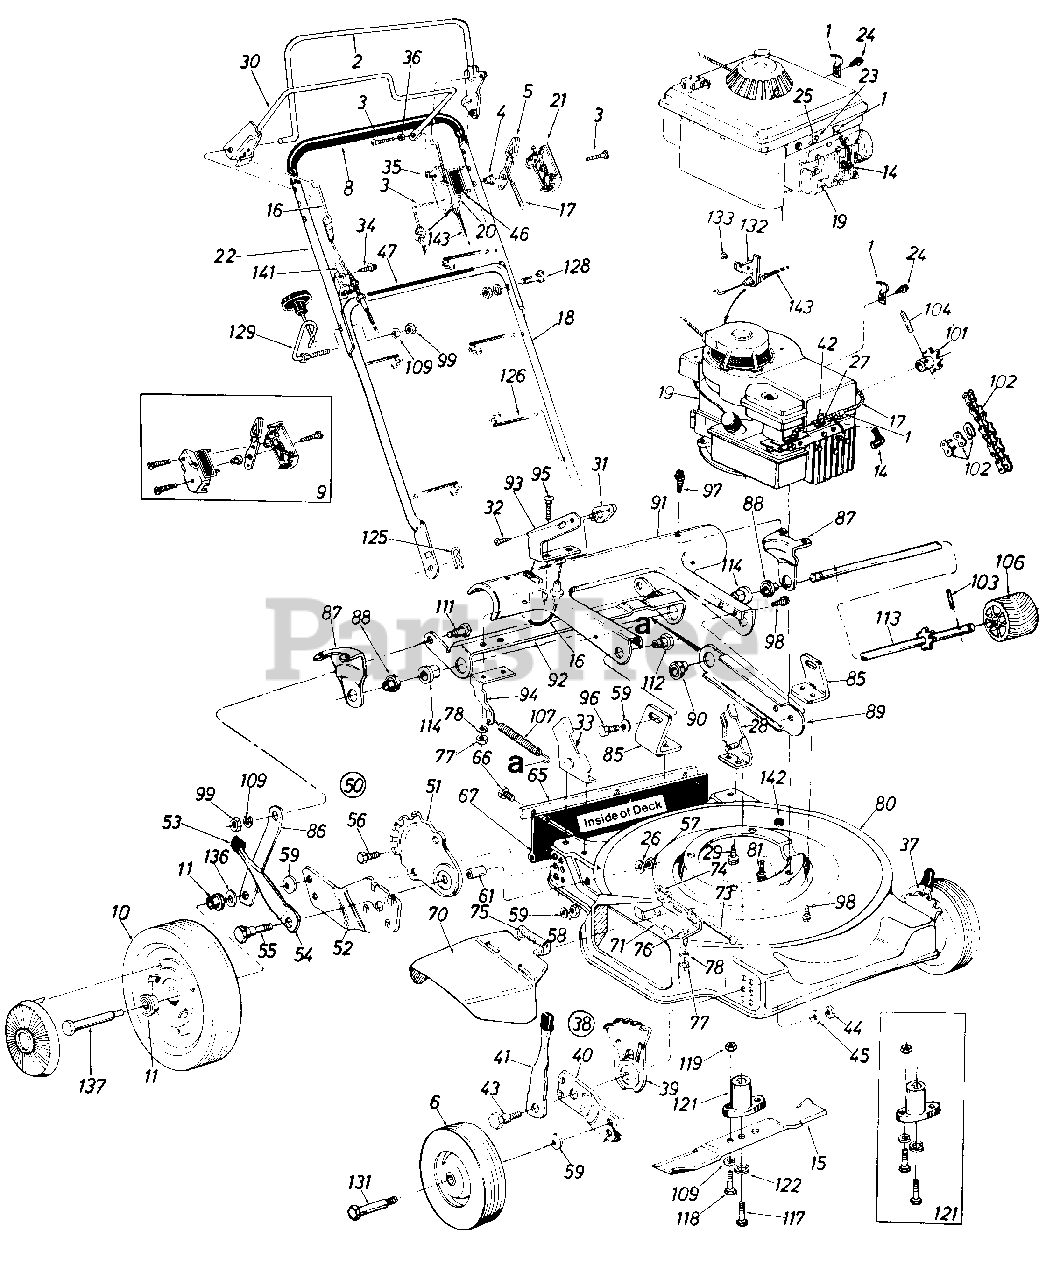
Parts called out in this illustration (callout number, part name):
1	Casing Clamp
2	Control Handle Ass'y.-L.H.
3	Truss Mach. Hi-B Tap Scr. #12 x 1.5"
4	Control Disc Pin
5	Throttle Control Lever
6	Front Wheel Ass'y. Comp.
8	Grip
9	Control Housing Comp.
10	Rear Wheel Ass'y. Comp.
11	Fl. Ball Brg. 1/2" I.D.
14	Spark Plug Insulator
15	22" Blade
16	Clutch Cable w/Spring-33"
17	Throttle Wire-53"
18	Lower Handle (Chrome)
19	Engine
20	Clutch Panel Half
21	Control Panel Half
22	Upper Handle (Chrome)
23	Hex AB-Tap Scr. #8 x .50"
24	Hex B-Tap Scr. #10 x .38"
25	Casing Clamp
26	Bell-Wash. 5/16" I.D.
27	Hex "B"-Tap Scr. #10 x .38"
28	Handle Brkt. Ass'y-L.H.
29	Hex B-Tap Scr. 5/16-18 x .5"
30	S.P. Bail Ass'y.
31	Barrel Cable Hold-Down R.H.
32	B-Tap Scr. #10 x .38 Lg.
33	Handle Brkt. Ass'y-R.H.
34	Hex Wash. AB-Tap Scr. 5/16 x .75"
35	Spr-Wash. .206 I.D. x .448
36	Spacer .23 I.D. x .30 O.D.
37	Front Height Adj. Ass'y.-L.H.
38	Front Height Adj. Ass'y.-R.H.
39	Height Adj. Plate
40	Pivot Bar
41	Spring Lever Ass'y. w/Knob
42	Casing Clamp
43	Shld. Bolt .50 Dia. x .430
44	Hex Nut 3/8-16 Thd.
45	Bell-Wash. .39 I.D. x 1.38 O.D.
46	Control Label
47	Instruction Label
50	Rear Height Adj. Ass'y.-R.H.
51	Index Plate
52	Pivot Bar-R.H.
53	Spring Lever Knob
54	Spring Lever
55	Shld. Bolt .50 Dia. x .433
56	Hex Bolt 3/8-16 x .75
57	Hex Cent. L-Nut 5/16-18 Thd.
58	Hex Nut 3/8-16 Thd.
59	Bell-Wash. .40 I.D. x .88 O.D.
61	Spacer .383 I.D. x .503 O.D.
65	Retaining Strip
66	Hex AB-Tap Scr. 1/4 x .62
67	Rear Flap Ass'y.
70	Chute Deflector Ass'y.
71	Adapter Plate
73	Pivot Pin
74	Push Nut 1/4"
75	Torsion Spring
76	Hex Bolt 1/4-20 x .50 Lg.
77	Hex Nut 1/4-20 Thd.
78	L-Wash. 1/4 I.D.
80	22" Deck Ass'y
81	Hex TT-Tap Scr. 3/8-16 x 1.0
85	Pivot Brkt.
86	Link
87	Axle Brkt.
88	Fl. Ball Brg. 1/2" I.D.
89	Brg. Support
90	Fl. Ball Brg. 1/2" I.D.
91	Pinion-Pivot Cover
92	Drive Engagement Cam
93	Engagement Arm-L.H.
94	Spring Bracket
95	Carriage Bolt 1/4-20 x .62
96	Hex Bolt 3/8-16 x .50 Lg.
97	Hex AB-Tap Scr. 1/4 x .62
98	Hex AB-Tap 1/4 x .62"
99	Hex Nut 5/16-18 Thd.
101	1OT Sprocket Ass'y.
102	#48 Chain 1/2" Pitch 50 Links
103	Spring Pin Spir. 3/16 Dia. x 1 .25
104	Spring Pin Spir. 3/16 Dia. x 1 .0
106	Drive Pinion
107	Extension Spring 4.25 Lg.
109	L-Wash. 5/16 I.D.
111	Shld. Bolt .437 Dia. x .162
112	Shld. Nut .625 Dia. x .165
113	Pinion Shaft w/7T Sprocket
114	Fl. Ball Brg. .501 I.D.
117	Hex Bolt 3/8-24 x 2.25
118	Hex Bolt 5/16-24 x 1.0-Spec.
119	Hex Nut 5/16-24 Thd.
121	Blade Adapter Kit
122	L-Wash. 3/8 I.D.-H.D.
125	Intern. Cot. Pin 5/16 Dia.
126	Cable Tie
128	Curved Carriage Bolt 5/16-18 x 1.38" Lg.
129	Rope Guide Bolt
131	Front Axle Bolt
132	Cable Bracket
133	Pop Rivet .156" Dia. x .379
136	Fl-Wash. .531 I.D. x .93 O.D.
137	Rear Axle Bolt
141	Cable Brkt.
142	Plastic Plug
143	Control Cable-39" (Green)
